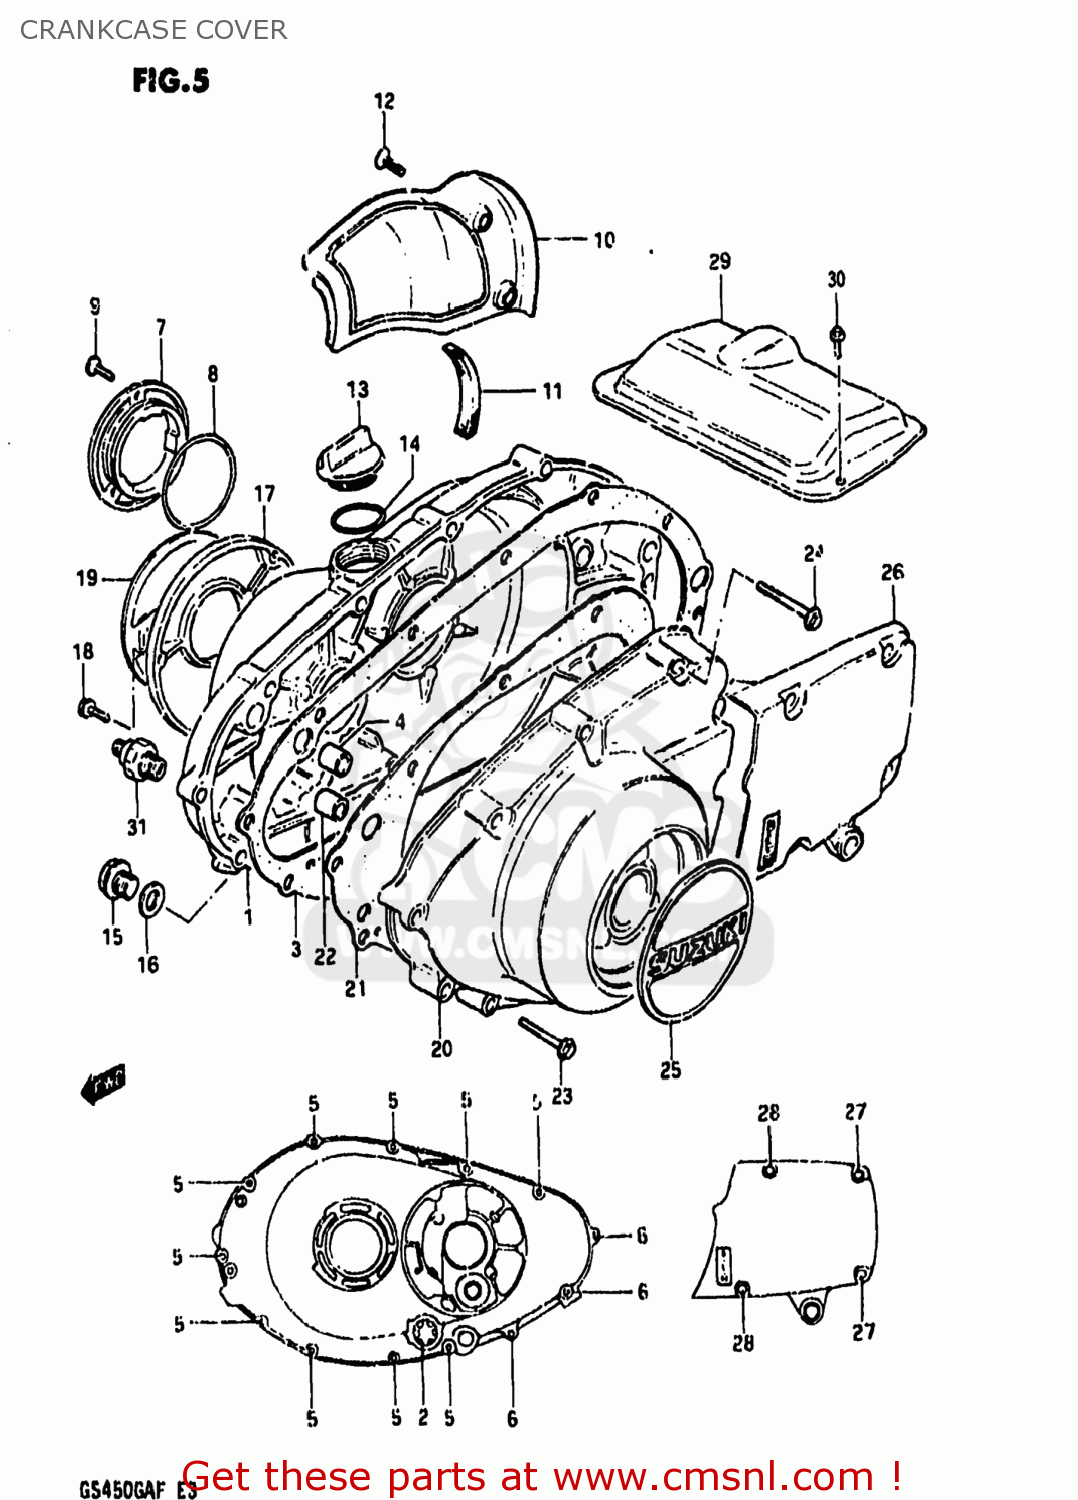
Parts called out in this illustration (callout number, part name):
1	COVER,CLUTCH
2	LENS,OIL LEVEL CHECK
3	GASKET,CLUTCH COVER (MCA)
4	PIN
5	BOLT (6X35)
6	BOLT
7	CAP,CARBURETOR INSPECTION
8	O RING(D:2.4,ID:52.6)
9	SCREW 5X16
11	GUARD,BELT COOLING DUCT,CENTER
12	SCREW
13	PLUG SET
14	O-RING
15	PLUG (14X12)
16	GASKET(14X19.2X2) (NAS)
17	COVER,CONTACT BREAKER
18	BOLT
19	EMBLEM,MAGNETO COVER
20	COVER
21	GASKET,MAGNETO COVER (A
22	PIN
23	BOLT
24	BOLT (6X30)
25	EMBLEM,MAGNETO COVER
26	COVER,SPROCKET
27	BOLT (6X20)
28	BOLT
29	COVER,STARTER MOTOR
30	BOLT
31	SWITCH ASSEMBLY
